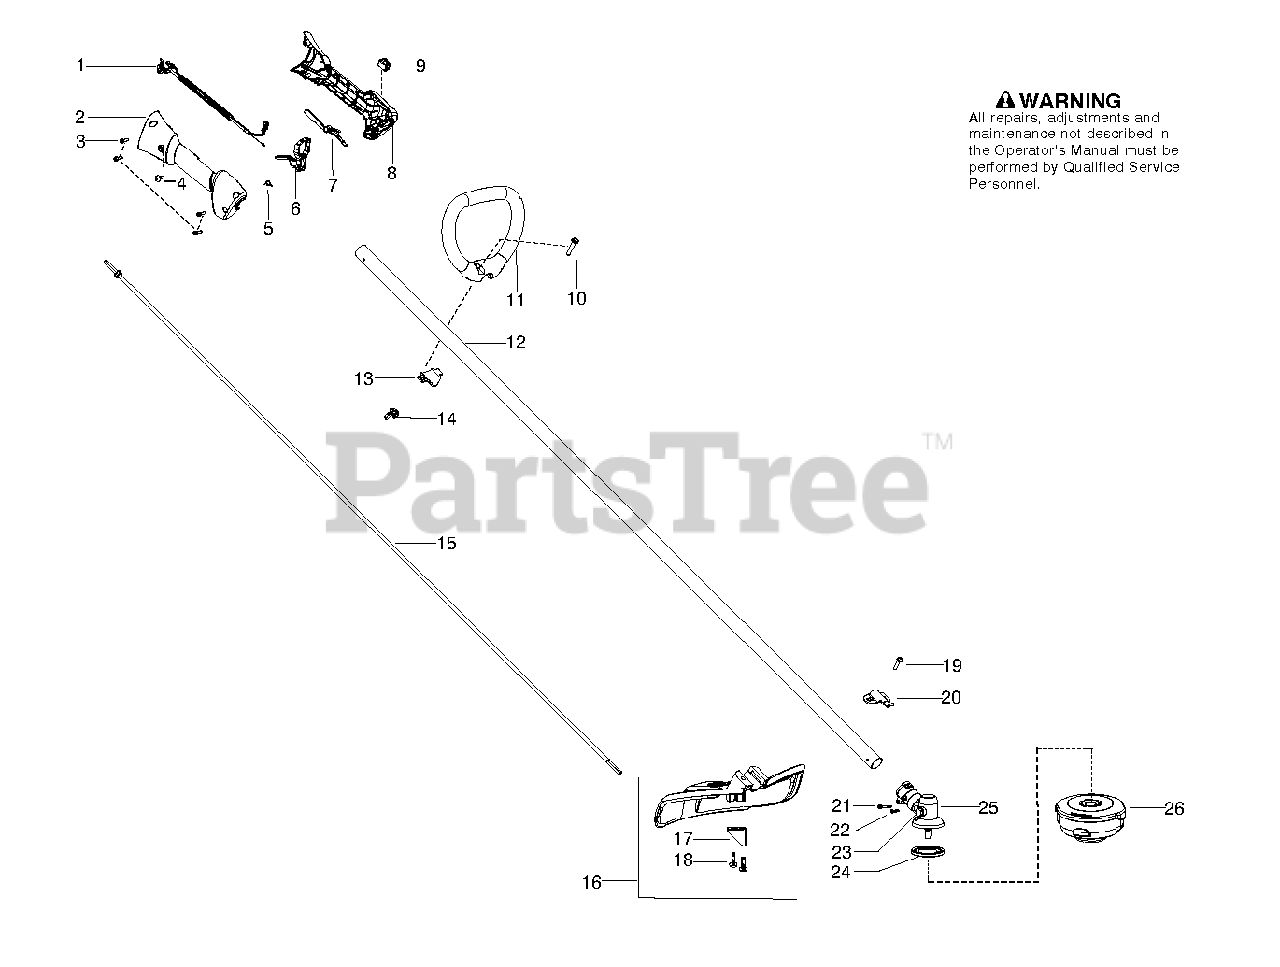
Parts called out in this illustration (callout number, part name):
1	ASSY CABLE / WIRE HARNESS
2	HOUSING RIGHT
3	SCREW M4 X 1.75 PT 16MM
4	SCREW-10-16 X 1/2, TYPE 2
5	SPRING TRIGGER
6	TRIGGER
7	THROTTLE LOCKOUT
8	HOUSING THROTTLE LH
9	SWITCH
10	BOLT, TYPE 2
11	HANDLE ASSIST
12	KIT DRIVE SHAFT SST US / CAN
13	CLAMP ASSIST HANDLE
14	WINGNUT, TYPE 2
15	FLEXSHAFT 57"
16	KIT SHIELD
17	LINE CUTTER
19	SCREW 1/4-20 X 7/8 (TAP
20	BRACKET SHIELD STRAIGHT SHAFT
21	SCREW - CARB. ADAPTOR
24	DRIVE DISC
25	ASSY GEARBOX
26	T25 TRIM HEAD 10MM LH
